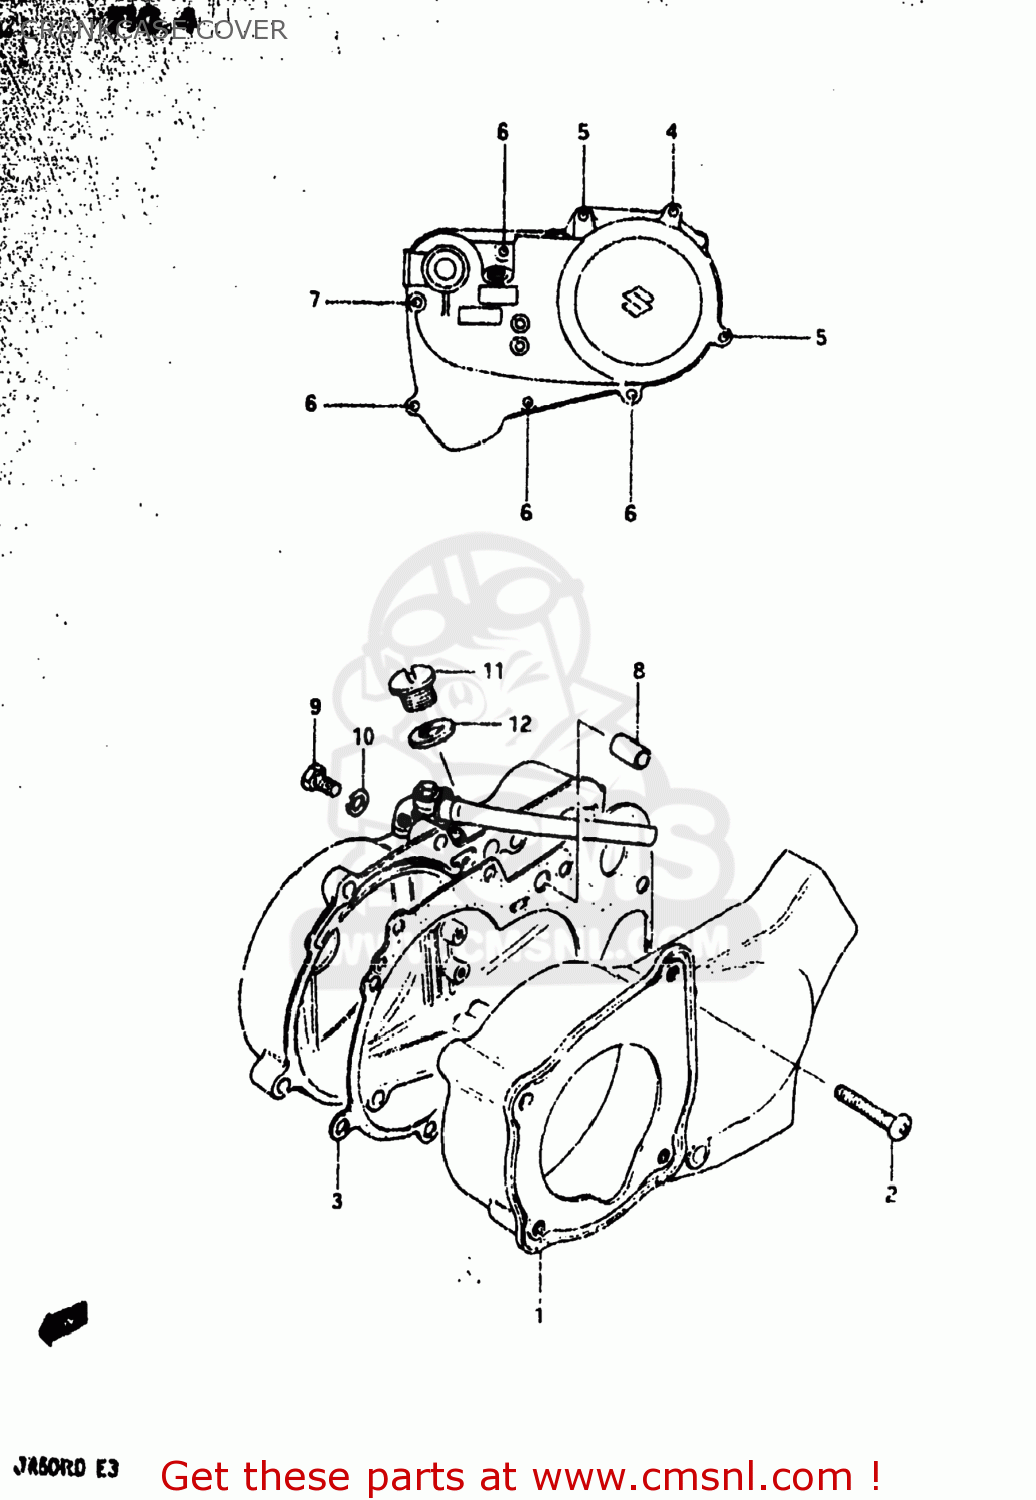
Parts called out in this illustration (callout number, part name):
1	COVER,MAGNETO
2	SCREW (6X35)
3	GASKET,CLUTCH COVER
4	SCREW
5	SCREW
6	SCREW 6X30
7	SCREW (6X45)
8	PIN
9	SCREW(6X10)
10	GASKET(6.2X11X1) (NAS)
11	PLUG
12	GASKET(14.5X20.5X1) (NAS)
